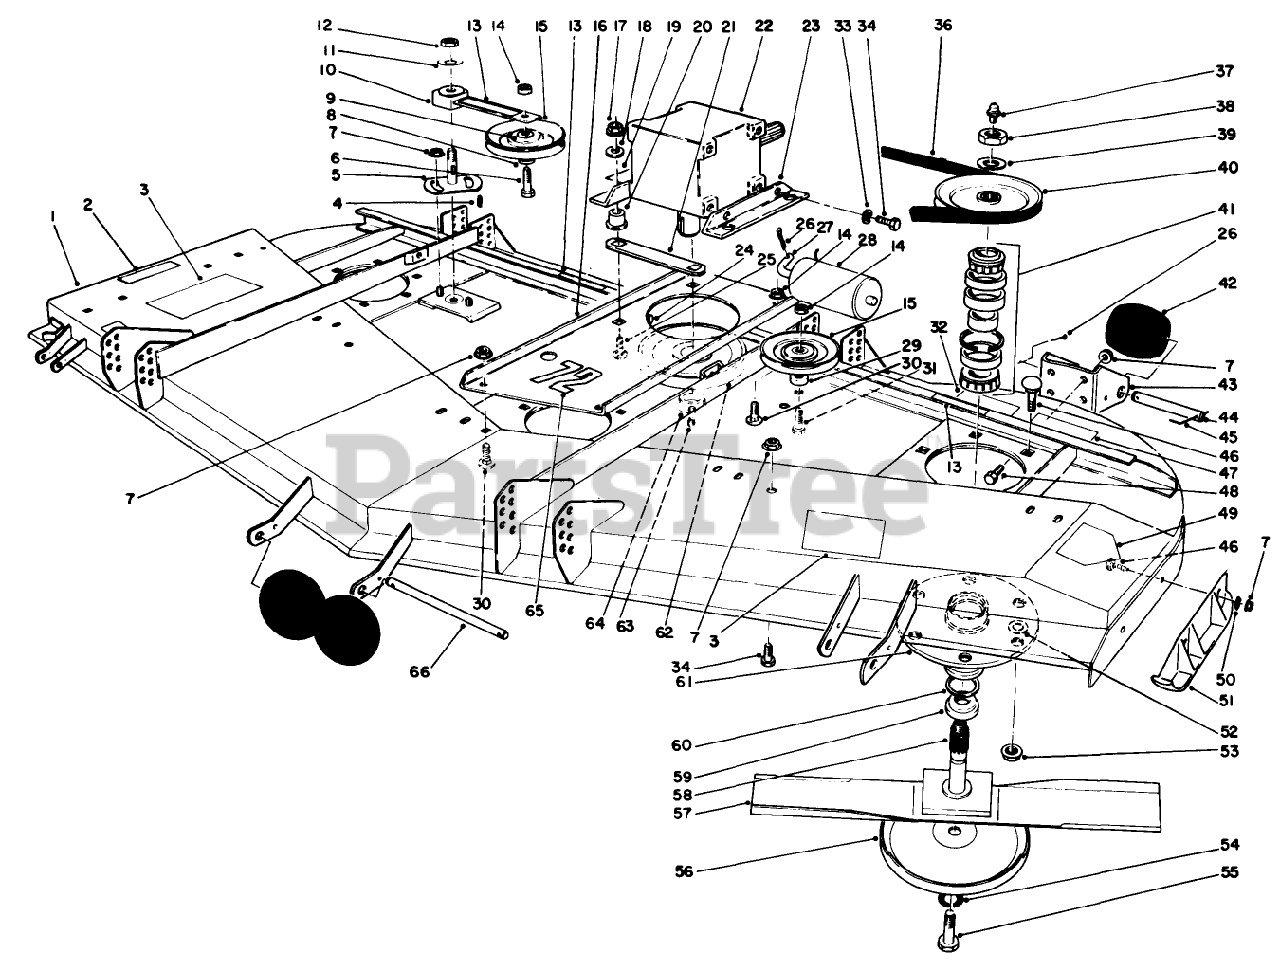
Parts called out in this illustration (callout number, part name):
1	Housing
2	DECAL-DANGER
3	DECAL-DANGER, THROWN OBJECT
4	KEY-SQUARE
5	PLATE-IDLER
6	SCREW-HH
7	NUT-HHF, WHIZ
8	BUSHING-PULLEY
9	WASHER-FLAT
10	IDLER ARM ASM
11	WASHER-FLAT
12	NUT-LOCK, NI
13	DECAL-DANGER
14	NUT-HEX
15	PULLEY-IDLER
16	Base-Gear Box
17	NUT-LOCK, SIDE
18	WASHER
19	DECAL-OIL
20	MOUNT
21	Cover-Gear Box
22	Gearbox
23	Bracket-Gearbox
24	KEY-WOODRUFF
25	SCREW-CARR
26	PIN-COTTER
27	SHAFT-ROLLER, REAR
28	ROLLER-DECK
29	SPACER
30	SCREW-CARR
31	SCREW-HH
32	DECAL-TORQUE
33	WASHER-LOCK
34	SCREW-HH
36	V-BELT (72)
37	FITTING-GREASE
38	NUT-HEX
39	WASHER
40	PULLEY & HUB ASM, WELDED
41	BEARING ASM
42	ROLLER
43	Bracket-Roller
44	SHAFT-ROLLER
45	PIN-SPECIAL
46	SCREW-CARR
47	DECAL - WARNING
48	SCREW-HH
49	DECAL-DANGER
50	LOCKWASHER-PYRAMID
51	Skid
52	WASHER-FLAT
53	NUT-HF
54	WASHER
55	SCREW-BLADE
56	CUP-SCALP, ANTI
57	Blade
58	SHAFT
59	SPACER
60	SEAL-OIL
61	HOUSING-SPINDLE
62	PULLEY
63	SCREW-SET, HSH
64	Bushing-Taper Lock (Incl. Ref. #63)
65	DECAL
66	SHAFT-ROLLER
